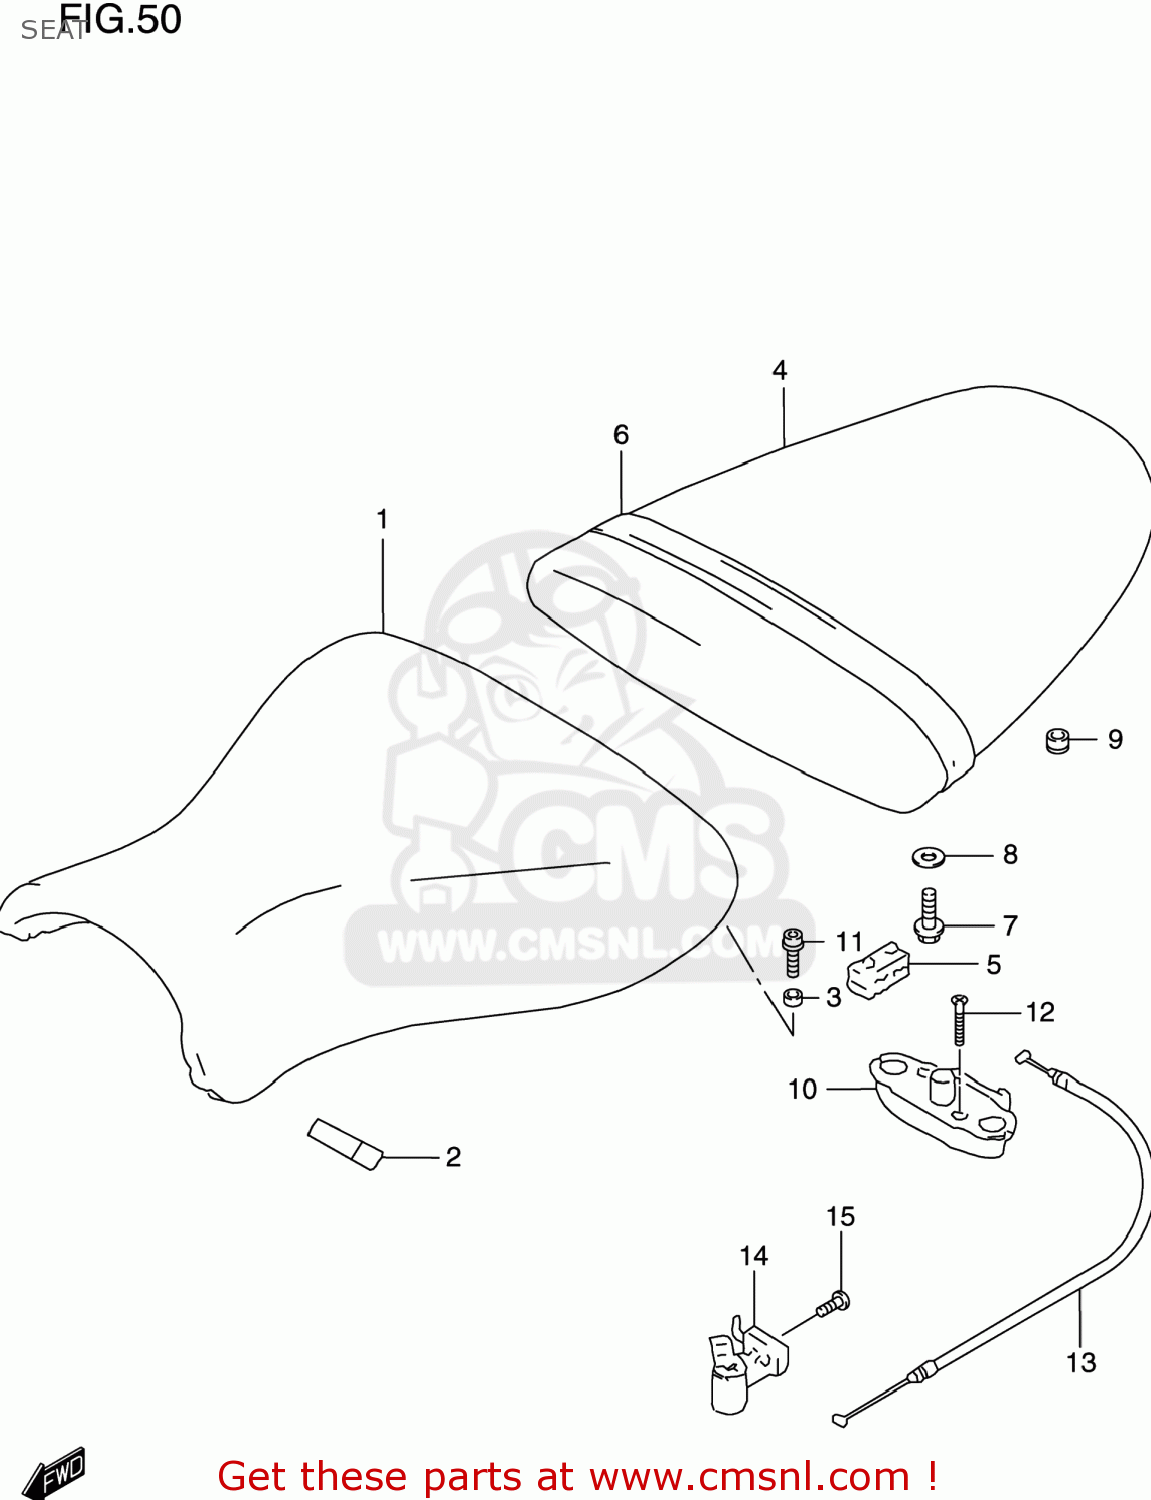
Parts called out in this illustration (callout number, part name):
1	SEAT ASSY(BLACK)
2	CUSHION,FR(20X40X15)
3	SPACER,SEAT(6.5X10.5X6)
4	SEAT ASSY,PILLION
5	CUSHION,SEAT(40X20X15)
6	BAND,SEAT
7	BOLT
8	WASHER(6.5X20X1.6)
9	CUSHION
10	BRACKET,SEAT SUPPORT,RIGHT
11	BOLT(6X18)
12	SCREW
13	CABLE,SEAT LOCK
14	LOCK SET,SEAT
15	SCREW
